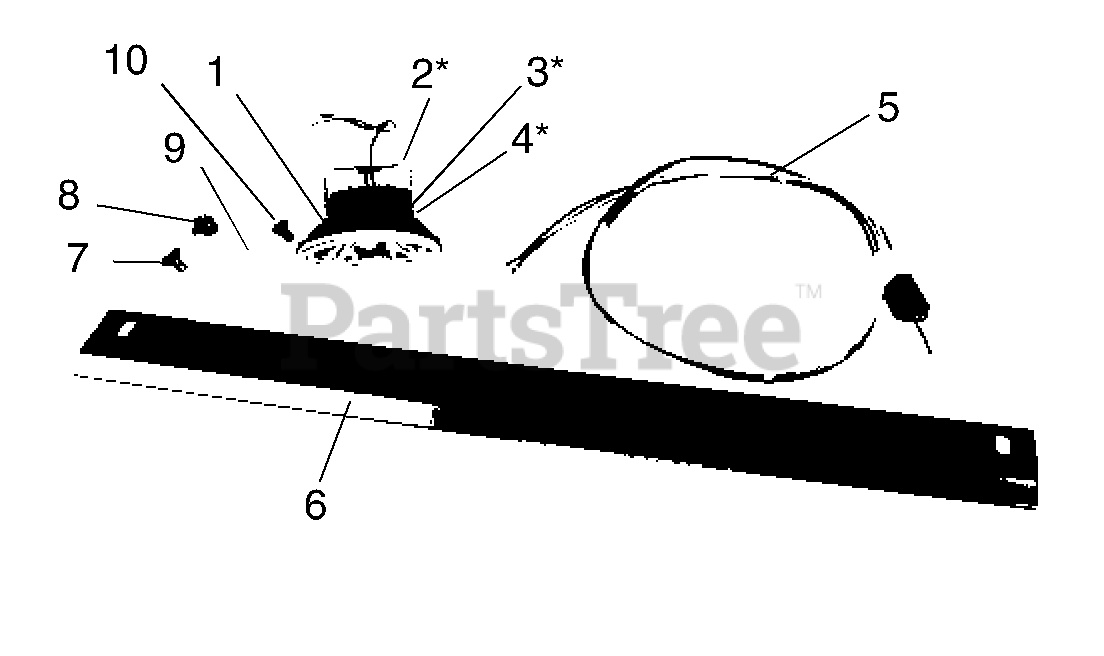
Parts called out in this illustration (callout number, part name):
1	Kit - Zoom LITE
2	Light Bracket Weldment
3	4 mm x 1 mm Regular Cone Lock Washer
4	4 mm x .07 mm x 8 mm Socket Head Cap Screw
5	Light Harness
6	Harness Bracket
7	5/16"-18 x 3/4" Round Head Square Neck Bolt
8	5/16"-18 Black Zinc Top Locking Flange Nut
9	5/16" x 5/64" Lock Washer
10	5/16"-18 x 1/2" Grade 5 Button Head Cap Screw
